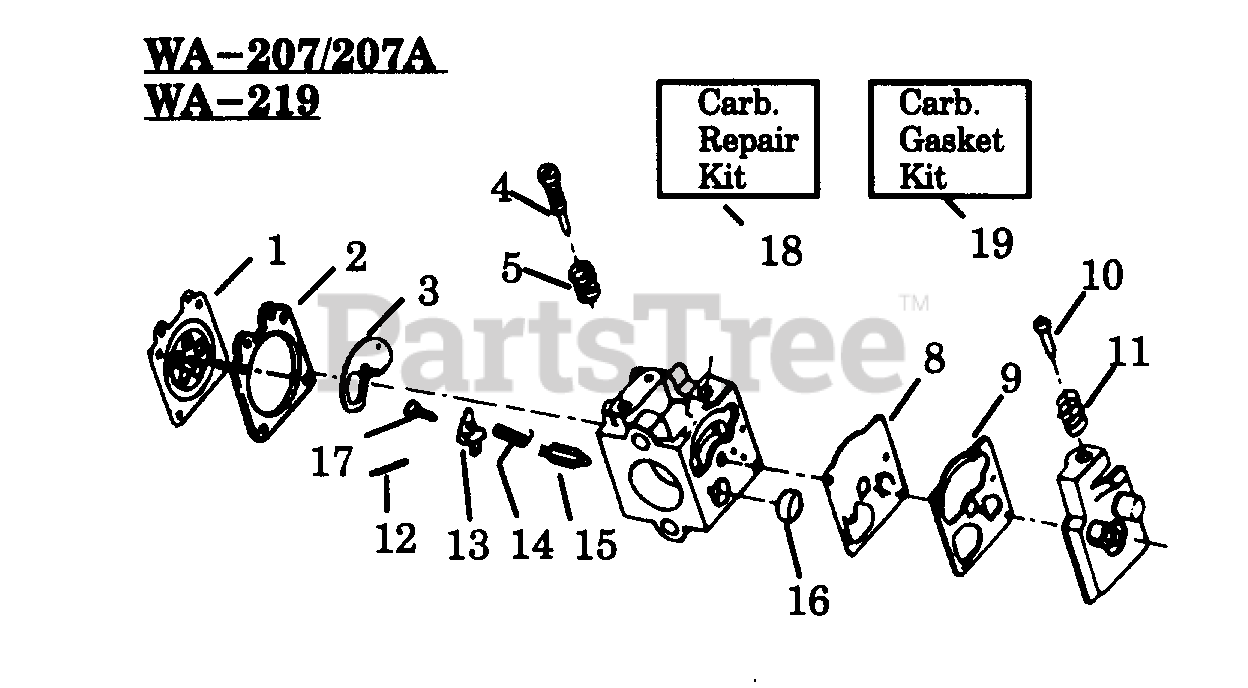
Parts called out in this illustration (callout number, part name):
1	Metering Diaphram
2	Metering Diaphragm Gasket
3	Circuit Plate Gasket
4	WA-207/207A
5	WA-207/207A
8	Fuel Pump Diaphragm
9	Fuel Pump Gasket
10	Idle Speed Screw
11	Idle Speed Spring
12	Metering Lever Pin
13	Metering Lever
14	Metering Lever Spring
15	Inlet Needle Valve
16	Fuel Inlet Screen
17	Metering Lever Pin Screw
18	Carb. Kwik Repair Kit (Inc. 1,2,3,8,9,12, 13,14,15,16,17)
19	Carb. Gasket/Diaphragm Kit (Inc. 1,2,3,8,9)
